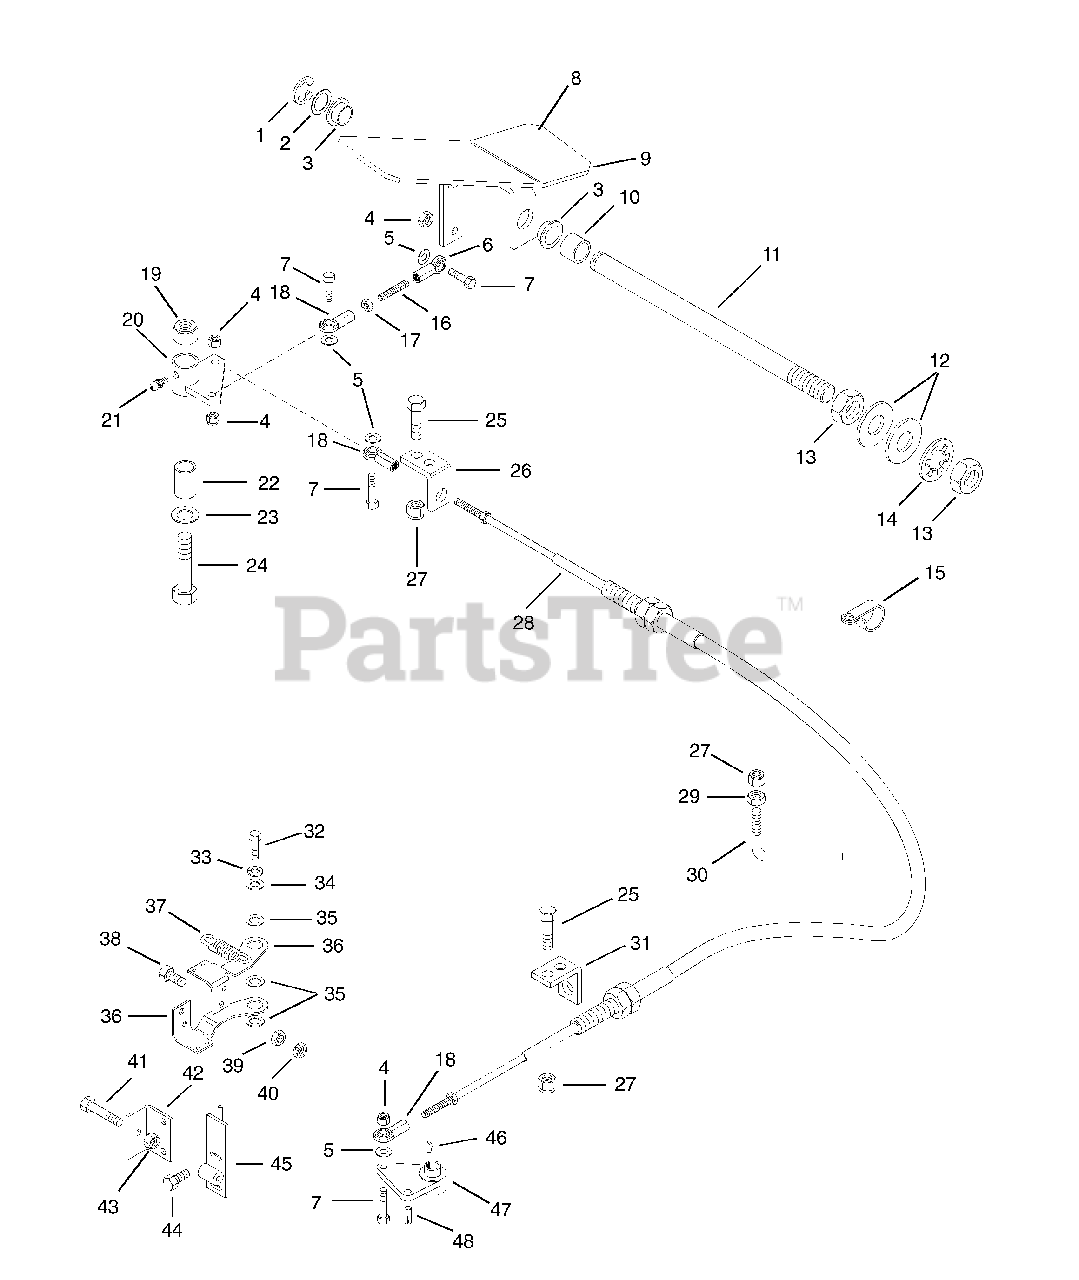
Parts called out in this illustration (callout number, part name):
1	Ring-Retaining-External .574 x .050
2	Bearing-Needle-Thrust .752 x 1.24 x .031
3	Bushing-Flange .762 x 1.0 x .580 x 1.48
4	Nut-Locking-Center .25-20
5	Washer-Flat-Steel .281 x .620 x .065
6	Rod End Left Hand
7	Bolt-Hex .31-18 x 1.75 Grade 5
8	Cover-Pedal
9	Weldment-Pedal
10	Bushing-Sleeve .782 x 1.00 x .710
11	Shaft-Pedal
12	Washer-Flat-Steel .812 x 1.50 x .139
13	Nut-Jam .75-16
14	Washer-Lock Internal .750
15	Clamp-Steel 1.0
16	Rod
17	Nut-Jam.25-28
18	Rod End-Female 1/4-28
19	Nut-Locking-Center .50-13
20	Weldment-Lever
21	Fitting-Lube .25-28 x .256
22	Spacer .562 x .855 x 1.56
23	Washer-Flat-Steel .50 x 1.25 x .083
24	Bolt-Hex .50-13 x 2.50 Grade 5
25	Bolt-Hex .38-16 x 1.00 Grade 5
26	Bracket-Cable
27	Nut-Locking-Center .38-16
28	Cable-Forward-Reverse
29	Nut-Jam .375-16
30	Rod-Cable Guide
31	Bracket-Cable
32	Bolt-Hex .25-20 x 1.50 Grade 5
33	Washer-Locking .25 x .062
34	Washer-Flat-Steel .281 x 1.250 x .048
35	Washer-Flat-Steel .760 x 1.25 x .030
36	Lever-Neutral
37	Spring-Tension .075 x .75 x 2.25
38	Bolt-Hex .31-24 x .75 Grade 5
39	Nut-Jam .312-24
40	Nut-Locking-Center .312-24
41	Bolt-Hex .31-18 x 1.25
42	Bracket
43	Nut-Locking-Nylon .312-18
44	Screw-Tapping .31-18 x .88 Hex Washer Head
45	Weldment-Neutral Stop
46	Key-Woodruff .13 x .50
47	Arm-Transmission Control
48	Pin-Groove .250 x .75
